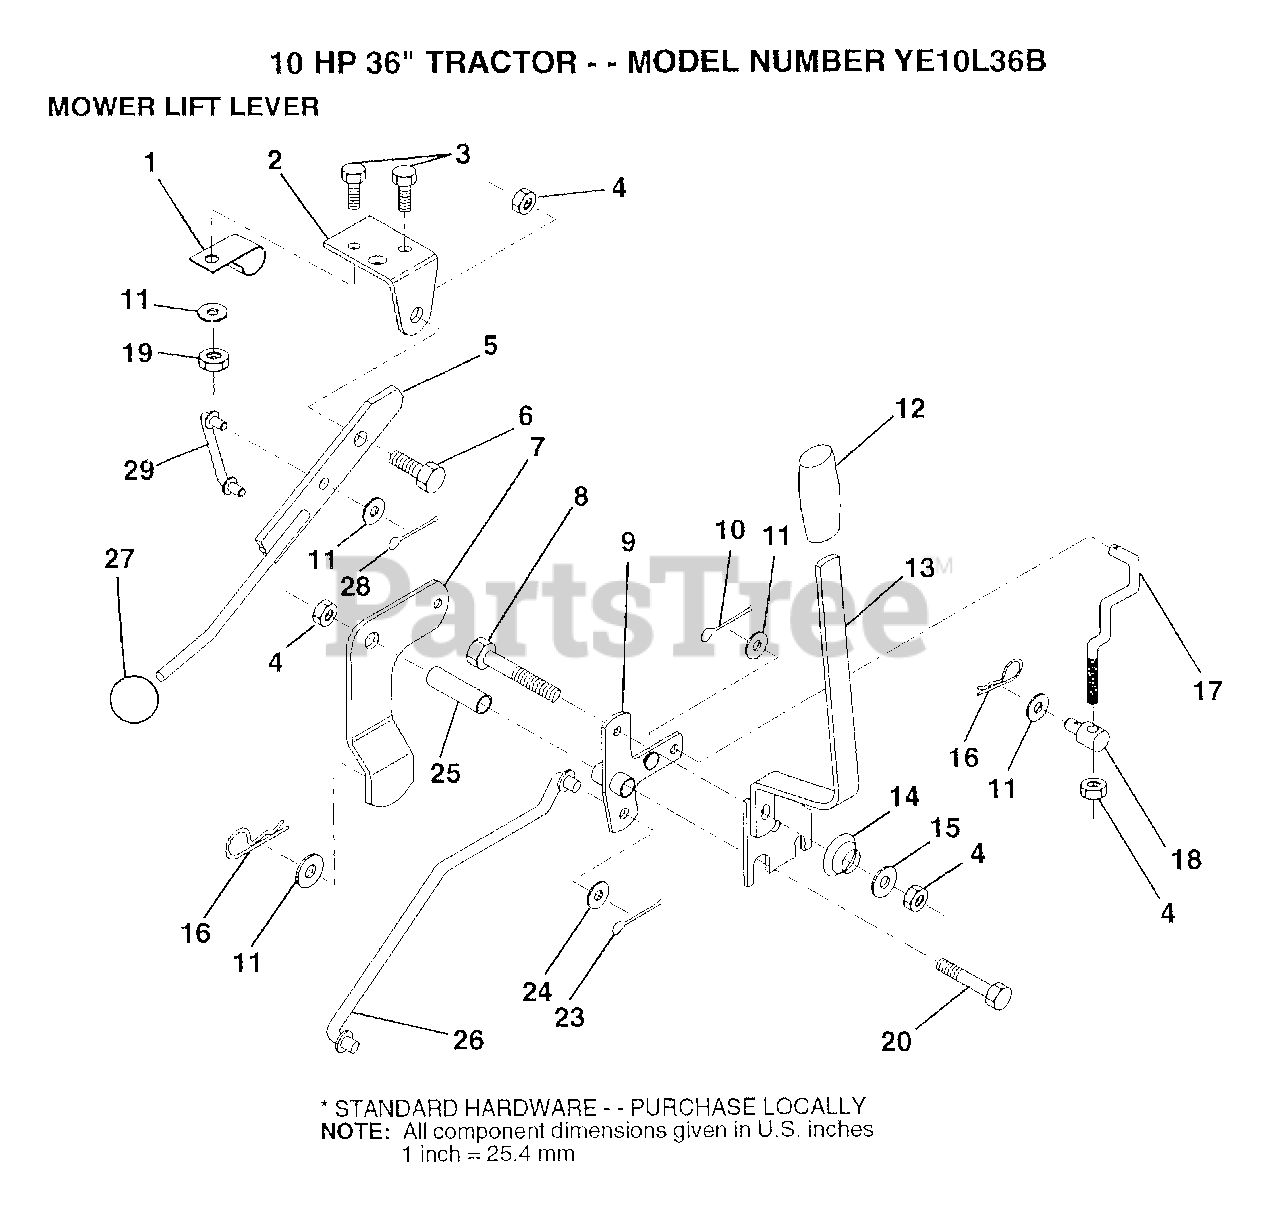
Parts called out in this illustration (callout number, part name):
1	"CLIP,INSULATOR"
2	BRKT CLUTCH
3	BOLT
5	CLUTCH LEVER AS
6	"BOLT, SHOULDER LT"
7	MWR CLUTCH ARM AS
8	BOLT
9	"BELLCRANK,LIFT"
10	COTTER PIN
11	WASHER
13	"HDLE,LIFT T"
14	SPRING COMPRESSIO
15	WASHER T
16	SPRING.RETAINER
17	"LINK,LIFT FRT"
18	TRUNION
20	BOLT
23	PIN COTTER 1/8
25	TUBE SPACER
26	"ROD,MOWER LIFT "
27	KNOB T(3/8 HOLE)
29	CLUTCH LINK
